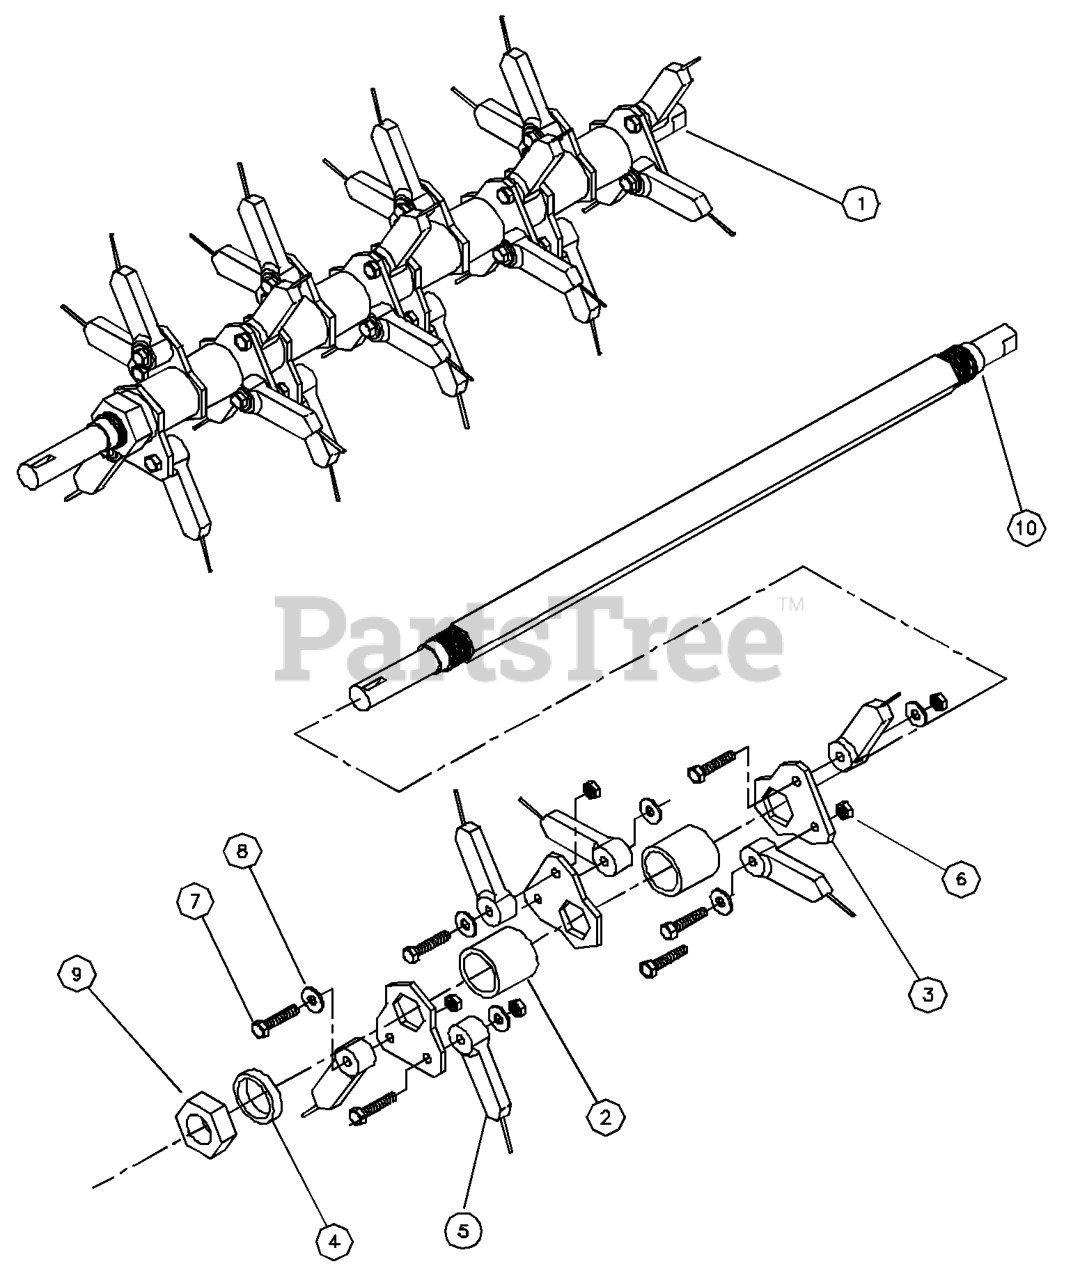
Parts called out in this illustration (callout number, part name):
2	SPACER - LONG
3	Plate, Spring Tine
4	Spacer, Short
5	SPRING TINE
6	NUT.1/4-20.HEX.NYLOC.ZD
7	BOLT HEX 1/4 X 1-1/4
8	WASHER 1/4 FLAT
9	JAM NUT W/SET SCREW
10	Shaft, Spring Tine
